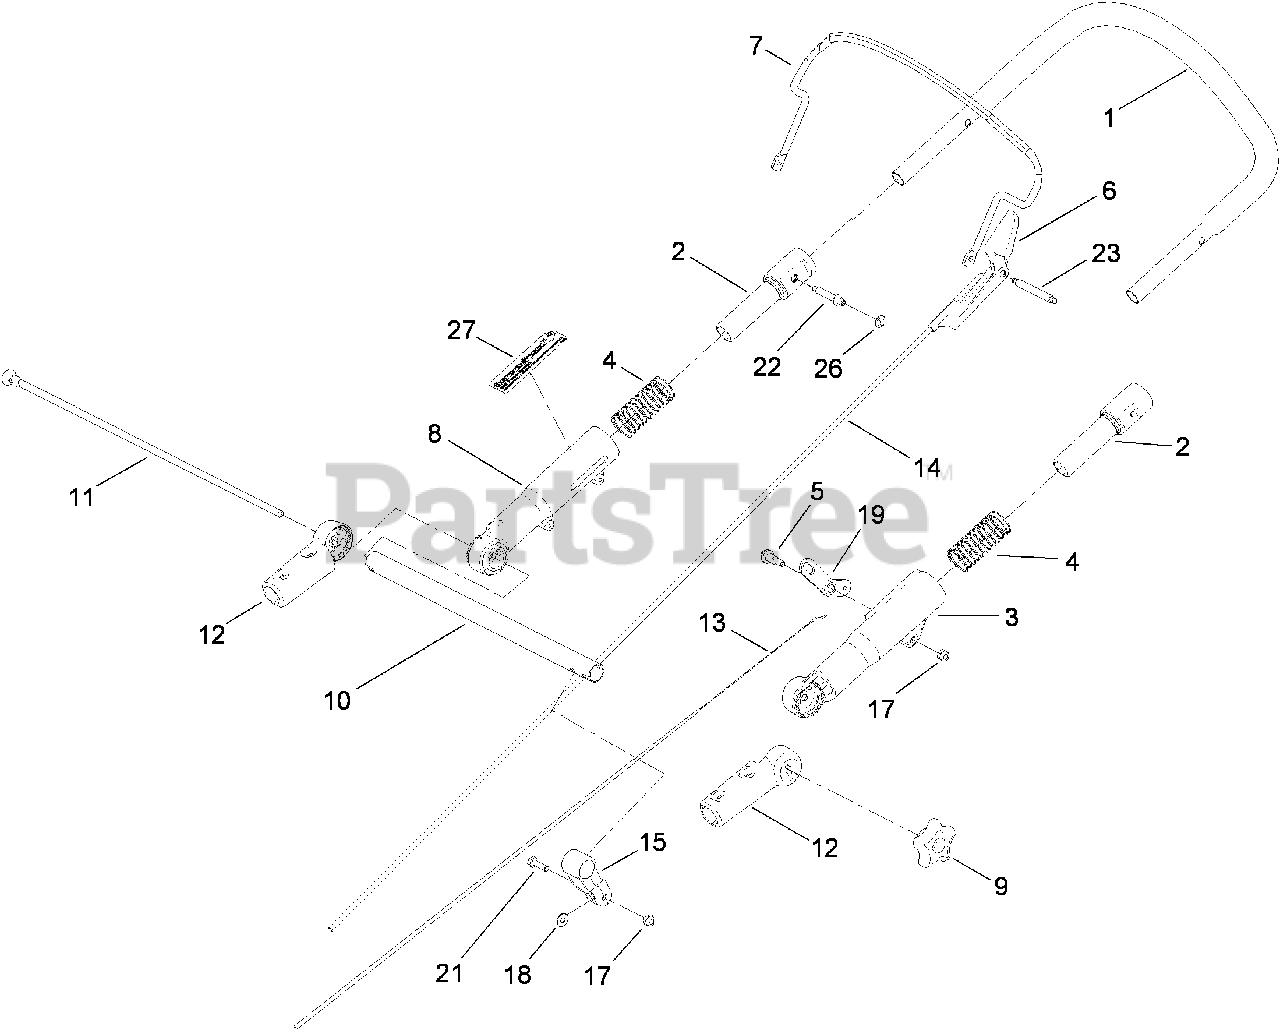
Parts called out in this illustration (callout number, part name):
1	UPPER HANDLE ASM
2	SLEEVE-INNER
3	SLEEVE-OUTER, LH
4	SPRING-COMPRESSION
5	BOLT-SHOULDER
6	STOP-PIVOT
8	SLEEVE-OUTER, RH
11	ROD-THREADED
12	MOUNT-HANDLE, LOWER
13	CABLE-TRACTION
14	CABLE-BRAKE
15	CLAMP-CABLE
17	NUT-LOCK, NI
18	WASHER-FLAT
19	LEVER-TRACTION
21	SCREW-HH
22	PIN-HANDLE
23	PIN-BAIL, LH
26	RETAINER-PUSH ON
